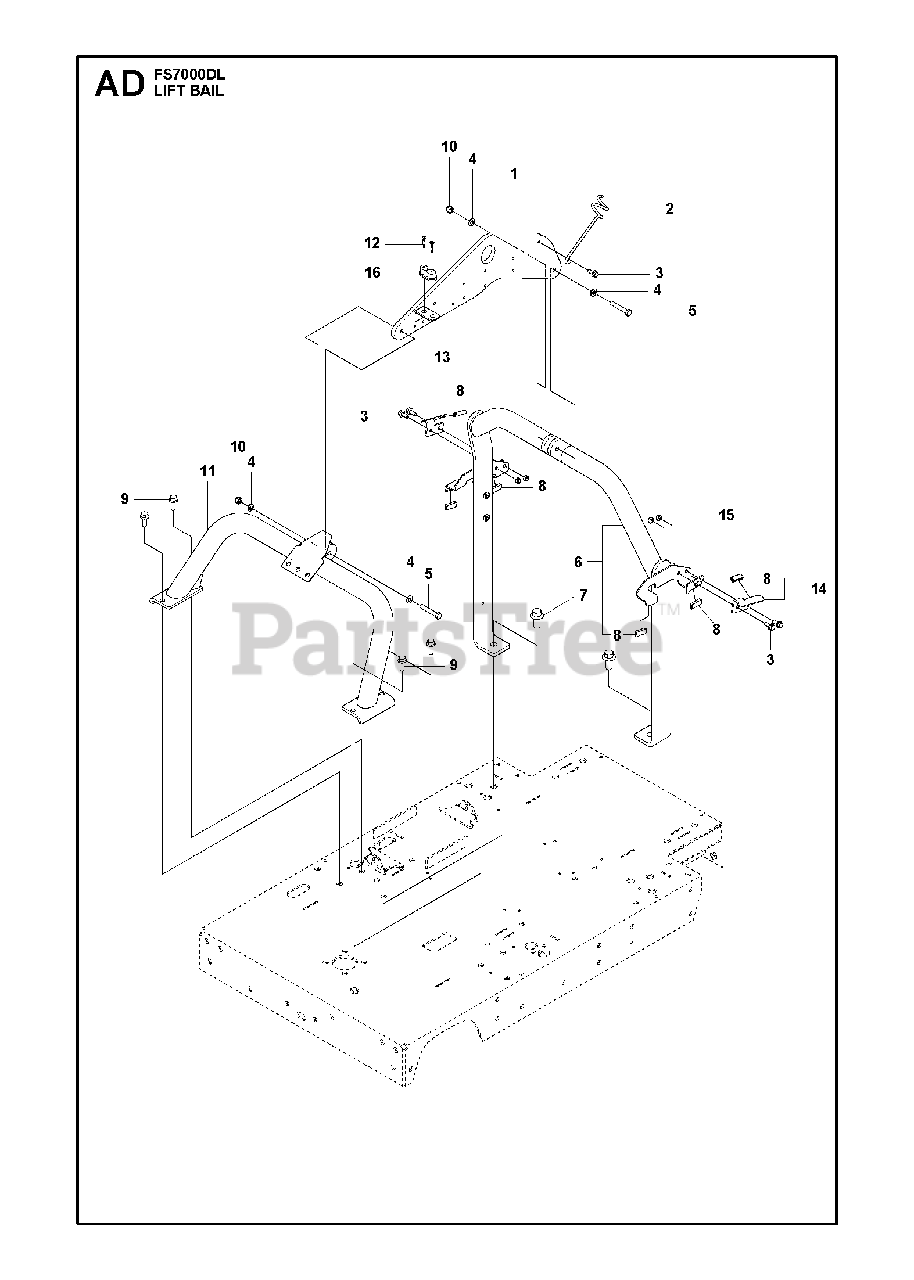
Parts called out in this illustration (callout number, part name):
4	WASHER
10	HEXAGON LOCKING NUT
15	HEXAGON LOCKING NUT
